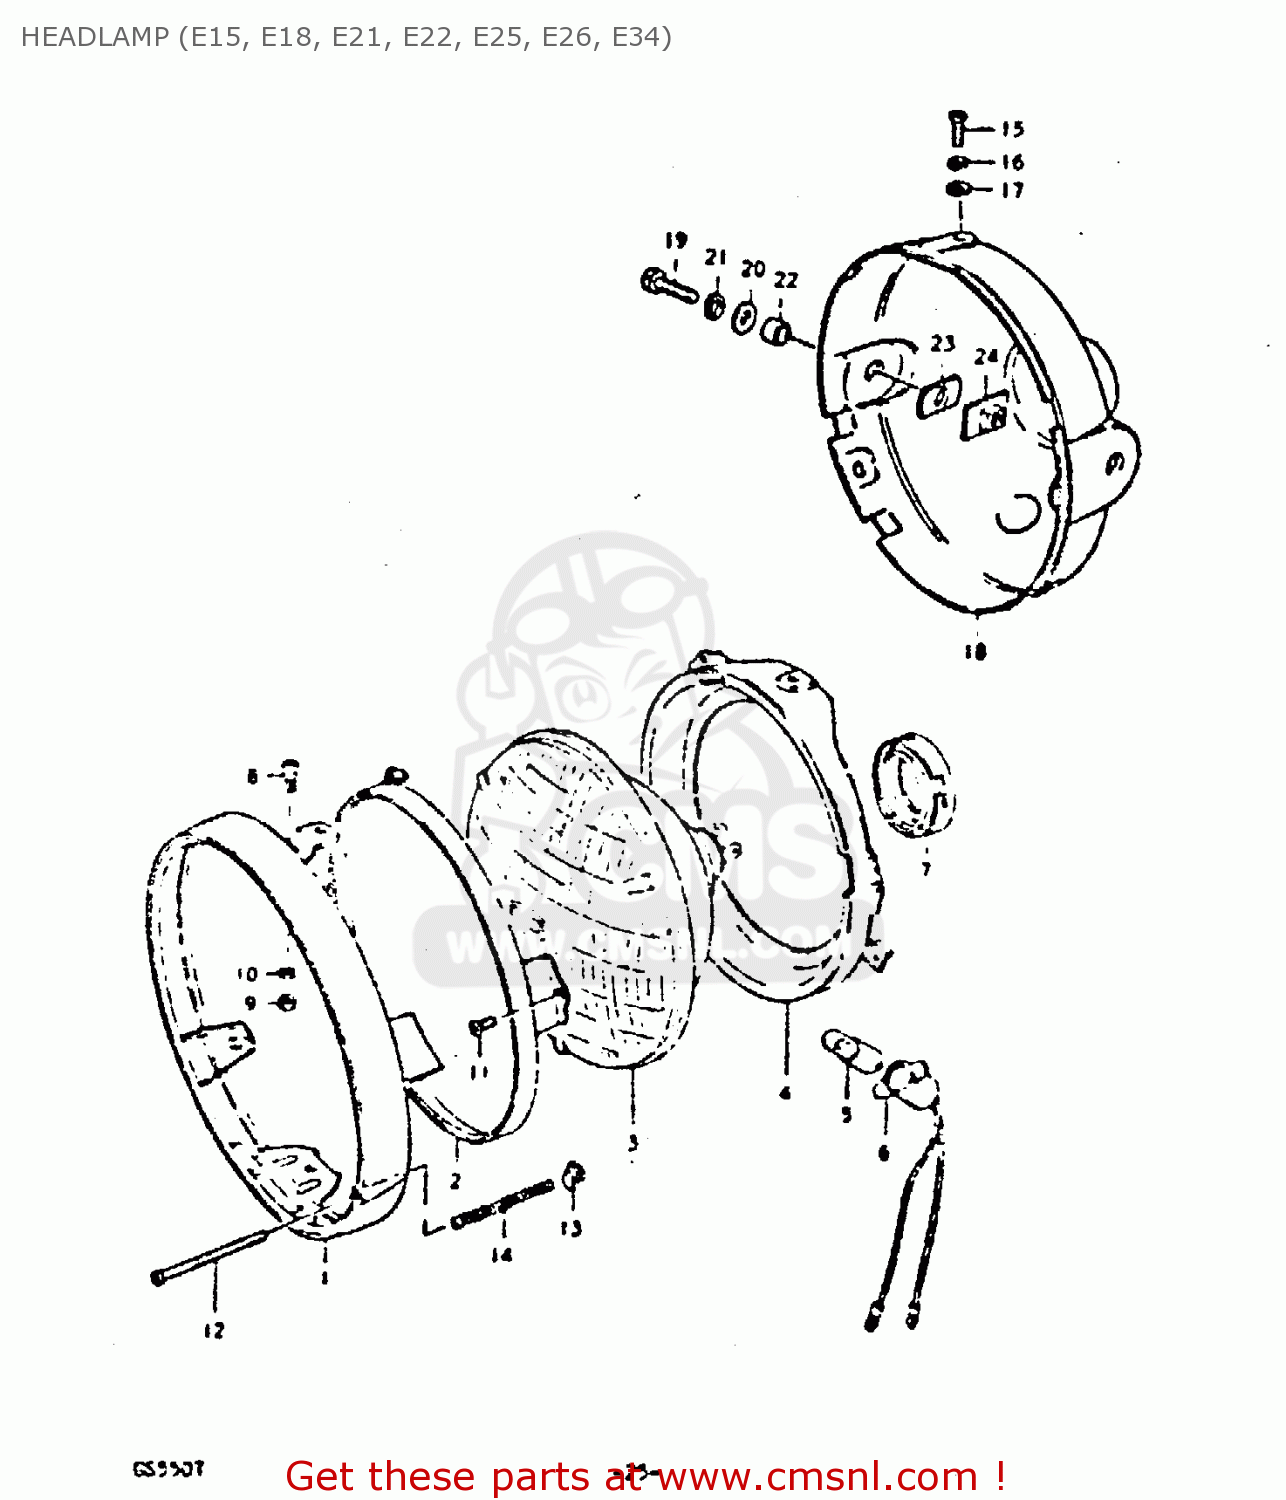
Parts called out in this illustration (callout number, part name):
1	RIM
2	RETAINING RING
3	UNIT
4	RING
5	BULB (EXECUTED LOCALLY 12V, 4W)
6	SOCKET
7	SETTER,BULB
8	H/LAMP LENS UNIT FITING SCRE
9	NUT
10	LOCK WASHER
11	SCREW
12	SCREW,HEADLAMP ADJUST
13	NUT
14	SPRING,ADJUSTING
15	SCREW
16	WASHER,LOCK
17	WASHER
18	HOUSING,HEADLAMP(BLACK)
19	BOLT
20	WASHER
21	LOCK WASHER
22	SPACER (8.8X12X7)
23	CUSHION
24	PLATE,HEADLAMP HOUSING
